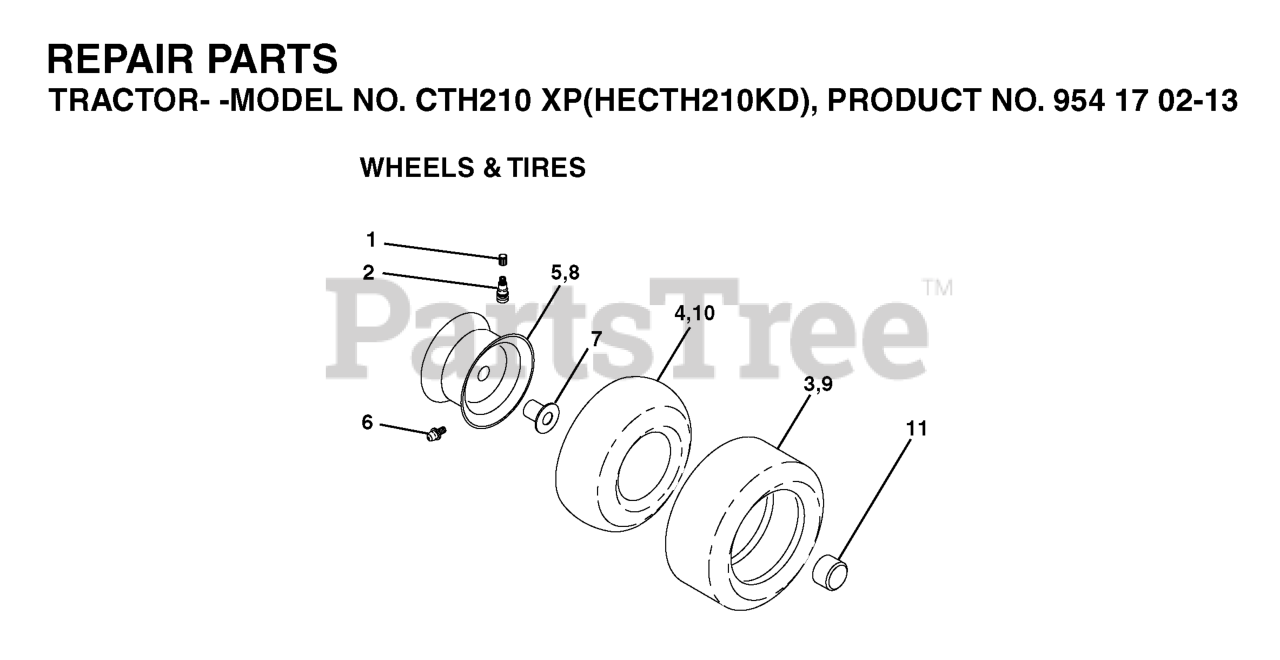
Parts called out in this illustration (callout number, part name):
2	VALVE STEM LT
3	TIRE HEAVY DUTY
4	TUBE.5.3/4.5/6
5	RIM ASM 6" FRONT SILVER
6	FITTING LT
7	BEARING T
8	RIM ASM 8" REAR SILVER
9	TIRE.TS.20X10-8
10	TUBE
11	CAP, AXLE BLK
